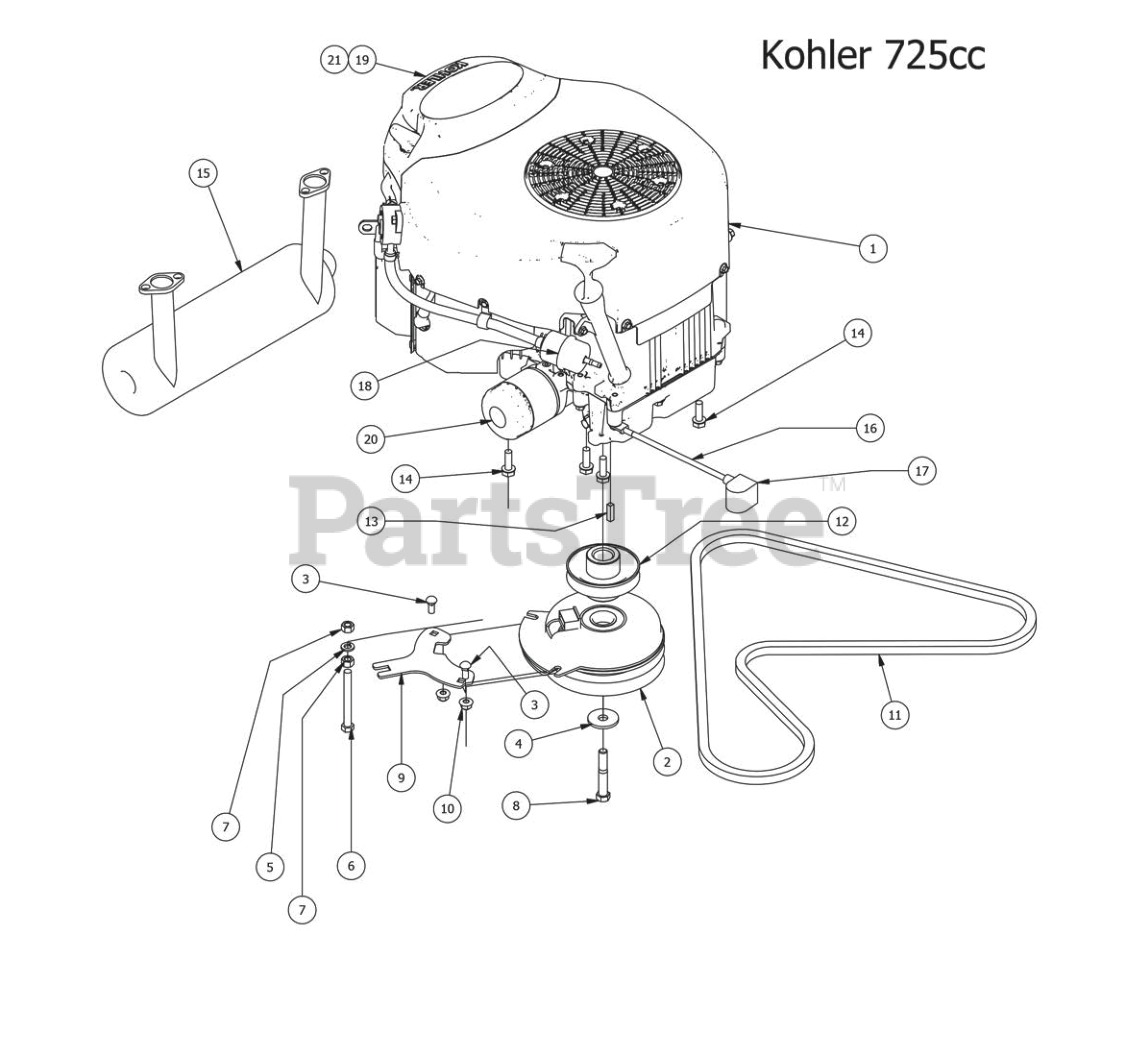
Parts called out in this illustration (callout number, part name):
1	Kohler-2014 Magnum 725cc
2	MZ Clutch Assembly
3	5/16-18x3/4 carriage bolt
4	1/2 Belleville Washer
5	3/8" Lock Washer
6	3/8-16x3-1/2 grade 5 hex bolt
7	3/8" Hex Nut
8	7/16x2 3/4 Fine Thread Bolt
9	MZ Clutch Holder
10	5/16" Nylon Flange Nut
12	3-3/4" Motor Pulley
13	1/4" x 1" Key
14	3/8 x 1 1/8 bolt
15	2014 MZ Muffler-725cc Kohler
16	Ground Cable
17	Black Boot For ground cable
18	725 & 747 Kohler Fuel Filter
19	725 & 747 Kohler Air Elemet ZT/MZ
20	725 & 747 Kohler Oil Filter ZT/MZ
21	725 & 747 Kohler Precleaner ZT/MZ
